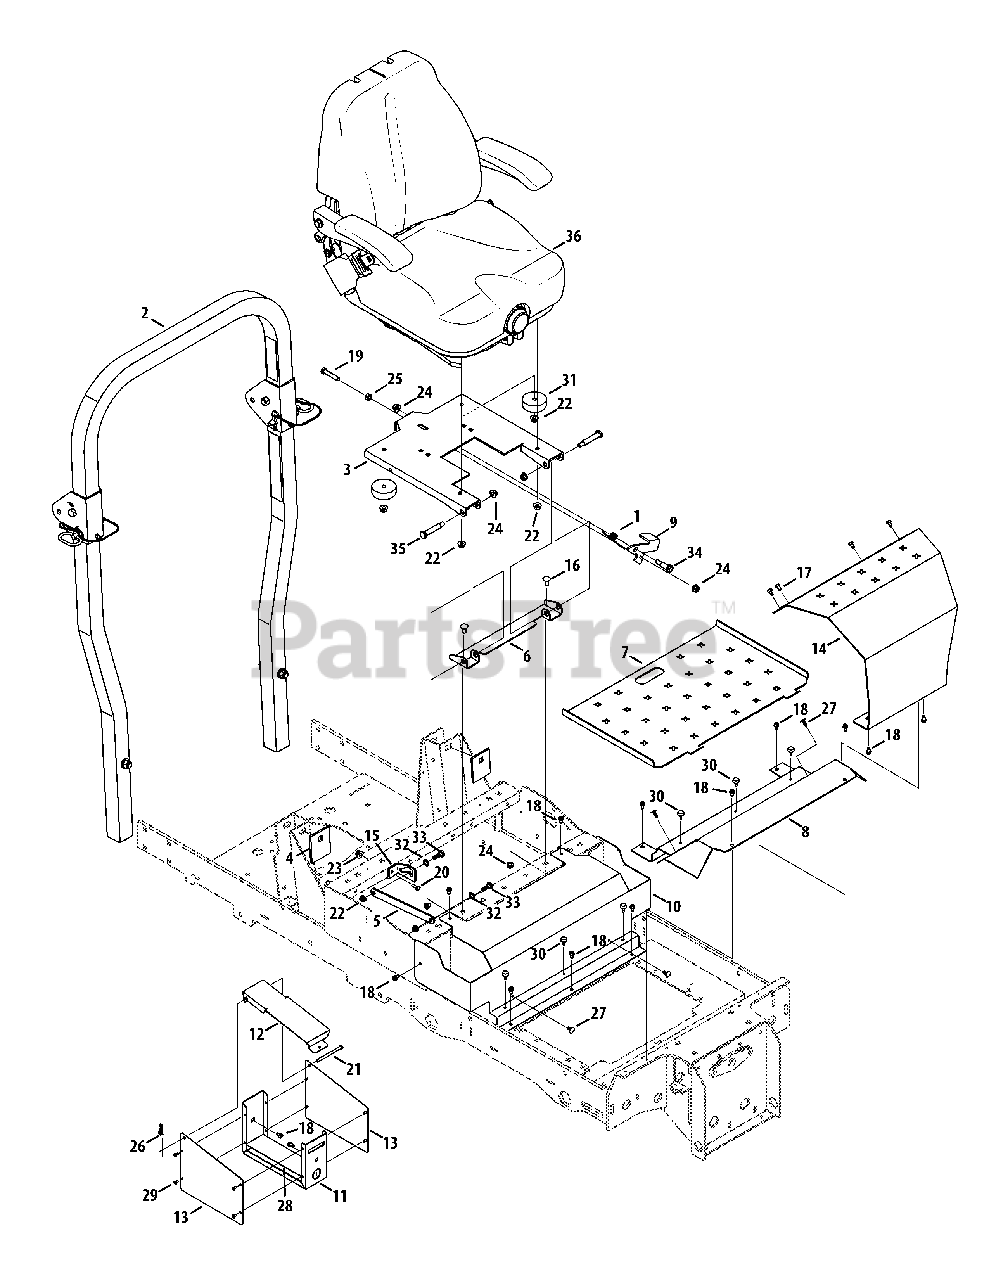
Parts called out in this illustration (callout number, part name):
1	Torsion Spring, .725 x 1.0 x .09
2	Folding ROPS Assembly
3	Seat Mounting Bracket
4	Deck Reinforcement Plate
5	Seat Lockout Bracket
6	Seat Mounting Bracket
7	Floor Panel Tray
8	Floor Panel
9	Seat Lever Latch
10	Control Panel Cover
12	Storage Box Lid
13	Storage Box Side Panel
14	Front Panel Cover
15	Seat Lockout Mount
16	Carriage Bolt, 3/8-16 x .75
17	Screw, 1/4-20 x .5
18	Hex Flange Screw, 1/4-20 x .500
19	Hex Cap Screw, 3/8-16 x 2.50
20	Hex Cap Screw, 1/4-20 x .75
21	Clevis Pin, .25 x 3.5
22	Nut, 5/16-18, Flangelock
23	Nut, 1/4-20, Flangelock
24	Nut, 3/8-16, Flangelock
25	Nut, 3/8-16, Hex
26	Cotter Pin, Bow Tie
27	Clip, .250 Dia.
28	Adhesive Pad
29	Rivet, 3/16 x .325
30	Bumper, .62 Dia. x .3
31	Rubber Bumper, 2.5 x 1.0
32	Flat Washer, .469 x .750 x .06
33	Shoulder Screw, 5/16-18 x .437 x .268
34	Shoulder Bolt, .50 x .925, 3/8-16
35	Shoulder Bolt, .500 x 2.23, 3/8-16
36	Seat
